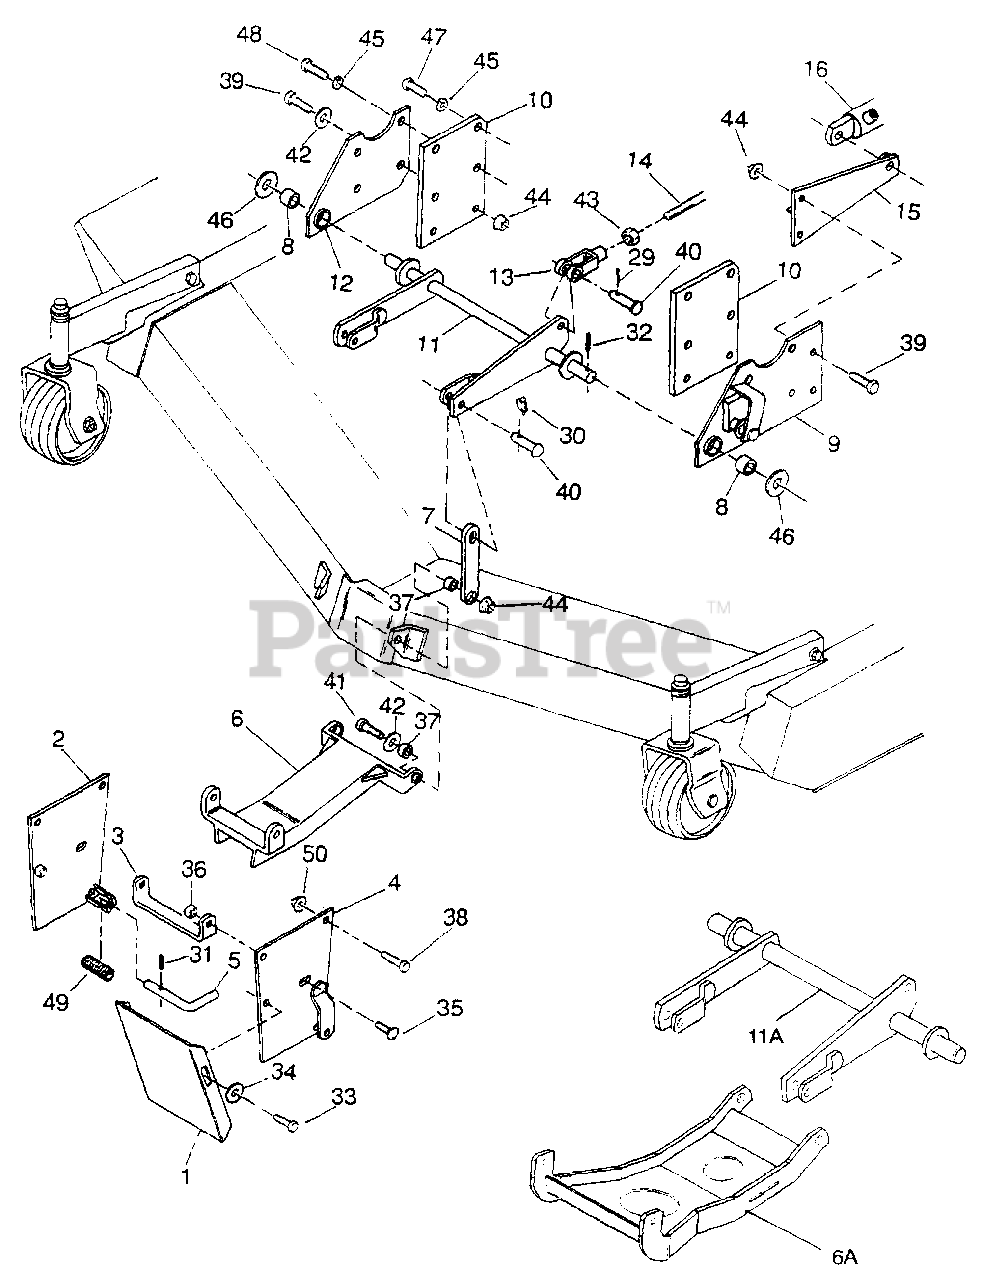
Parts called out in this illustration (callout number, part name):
1	Front mounting plate cover
2	Right front mounting bracket weldment
3	Mounting plate brace bar, 10.39
4	Left front mounting bracket weldment
5	Pin, Bent .5 dia. x 1.96
6	Front mounting channel assembly
6A	Front mounting channel
7	Mower lift bar, .38 x 1.5 x 6.5
8	1.015 x 1.25 x 1 Oilite bushing
9	Left front lift stop
10	Loader plate, .5 x 6.0 x 8.63
11	Front rockshaft assembly
11A	Front rockshaft
12	Right front lift stop
13	Adjustable clevis yoke, .50-13 x 3.0
14	Mower lift pull rod
15	Cylinder mounting bracket
16	Hydraulic cylinder
29	3/16 x 1 Cotter pin
30	3/16 x 1 Klik pin
31	3/16 x 1-1/8 Spring pin
32	1/4 x 2 Spirol pin
33	5/16 NC x 3/4 Hex head cap screw GR5
34	5/16 Standard flat washer
35	3/8 NC x 1-1/4 Carriage bolt
36	3/8 NC Hex locknut
37	1/2 x 3/4 x 1/2 Sleeve
38	5/8 NC x 1-1/2 Hex head cap screw GR5
39	1/2 NC x 1-3/4 Hex head cap screw GR5
40	1/2 x 1-3/4 Clevis pin
41	1/2 NC x 2 Hex head cap screw GR5
42	1/2 SAE Flat washer
43	1/2 NC Hex jam nut
44	1/2 NC Flanged hex locknut
45	9/16 Standard lockwasher
46	1" SAE Flat washer
47	14mm x 2.0 P x 35mm Hex head cap screw
48	14mm x 2.0 P x 40mm Hex head cap screw
49	Compression spring, .06 x .66 x 2.5
50	5/8 NC Hex locknut
